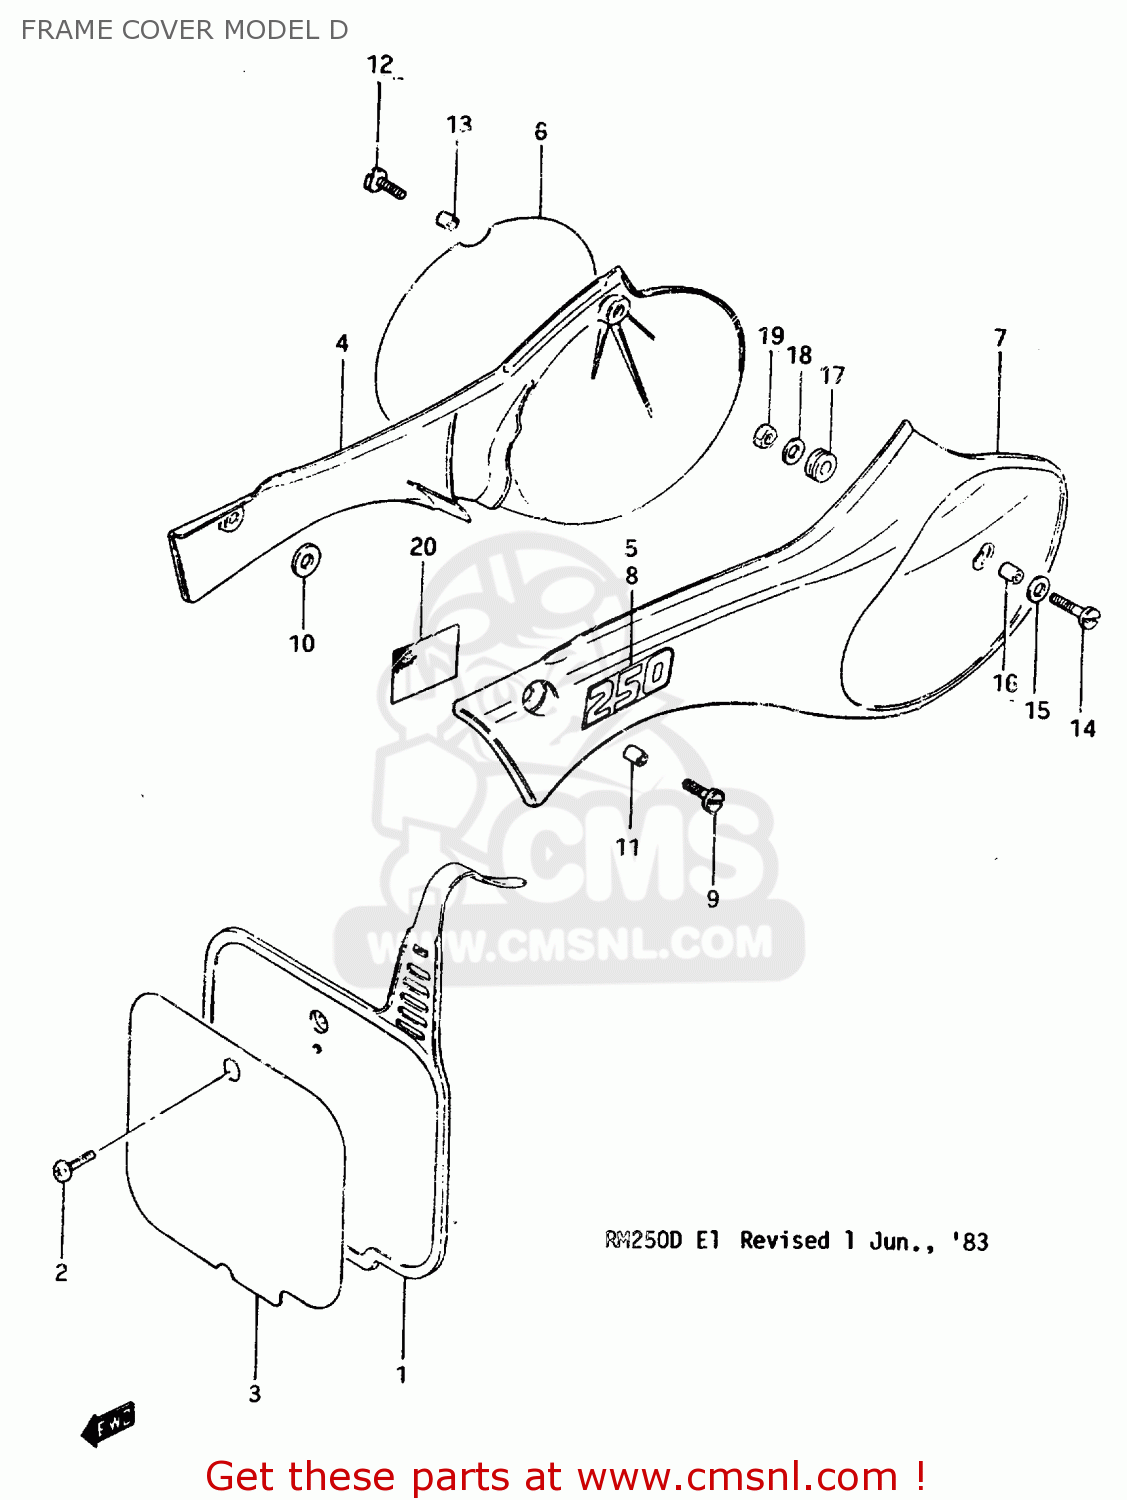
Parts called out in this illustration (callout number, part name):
1	PLATE,NUMBER,FRONT
2	SCREW
3	EMBLEM,FRONT NUMBER PLATE
4	COVER,FRAME,R(YELLOW)
5	EMBLEM,FRAME COVER,RIGHT
6	EMBLEM
7	COVER,FRAME,LEFT
8	EMBLEM,FRAME COVER
9	SCREW(6X14)
10	WASHER, REAR
11	SPACER (6.1X8X3.5)
12	SCREW(6X14)
13	SPACER (6.1X8X3.5)
14	SCREW(6X20)
15	WASHER (6.5X24X1.6)
16	SPACER (6.1X9X9)
17	CUSHION
18	WASHER, REAR
19	NUT 6MM
20	HEAT SHIELD,FRAME COVER
